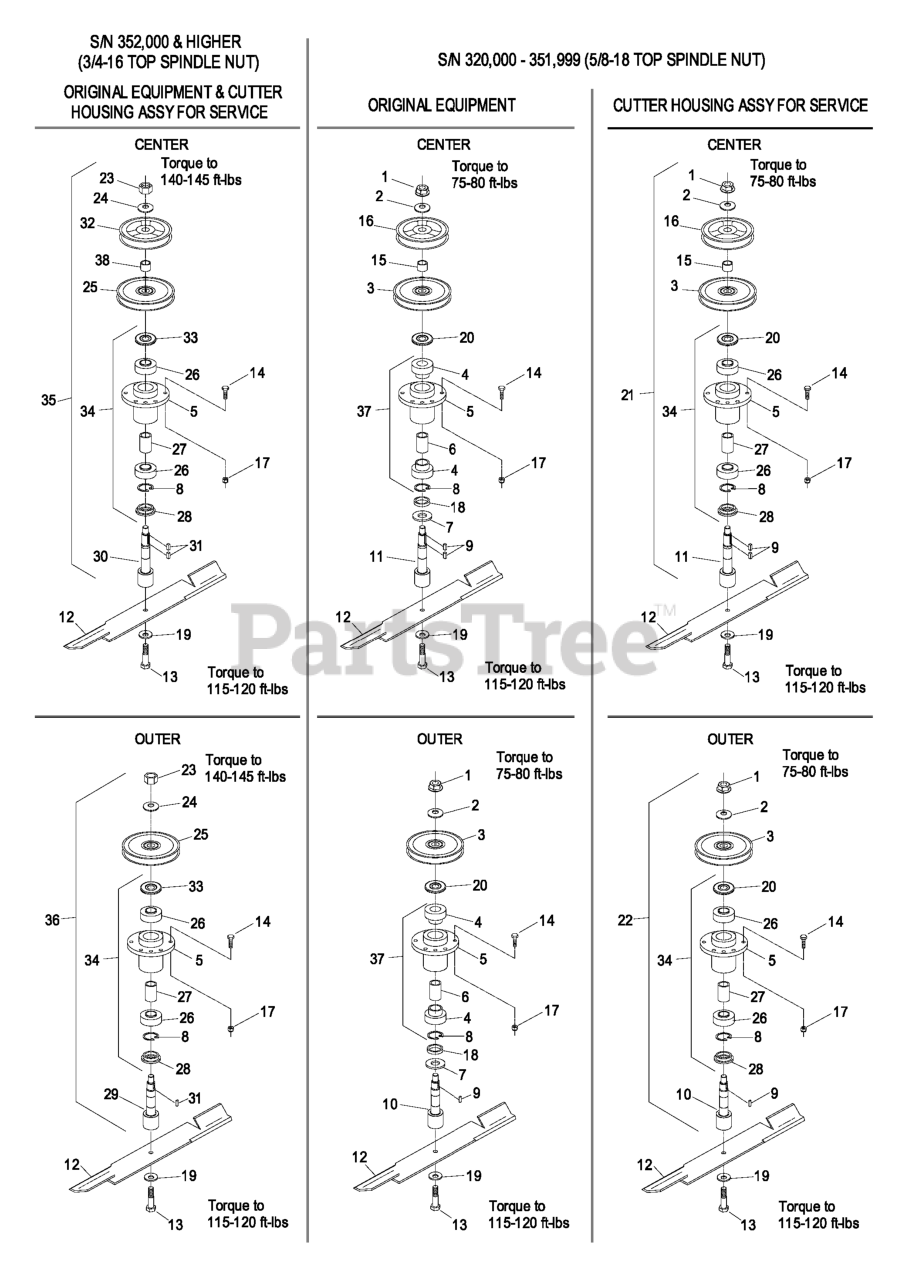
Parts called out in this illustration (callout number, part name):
1	NUT FLANGE
2	WASHER-SPRING
3	SHEAVE,BLADE DRIVE
4	BEARING
6	SPACER-BEARING
7	GUARD-BEARING, BOTTOM
8	RING-SNAP
9	KEY-SQUARE
10	SPINDLE,SHORT
11	SPINDLE,LONG
13	SCREW-CAP
14	SCREW-HH
15	SPACER-TUBE
16	SHEAVE,MOWER DRIVE
17	NUT-LOCK, NI
18	SPACER-PULLEY/BEARING
19	WASHER-BLADE BOLT, HEAVY
20	GUARD,BEARING TOP .880
22	ASM,SPINDLE HSG COMPLETE
25	SHEAVE,BLADE DRIVE 6.30
26	BEARING-JACKSHAFT
27	SPACER-BEARING
28	SPACER-GUARD, BOTTOM
29	SPINDLE,SHORT
30	SPINDLE,LONG
32	SHEAVE,MOWER DRIVE
33	GUARD-BEARING, TOP
37	Housing W/Brg Spacer & Ring
38	SPACER,TUBE
